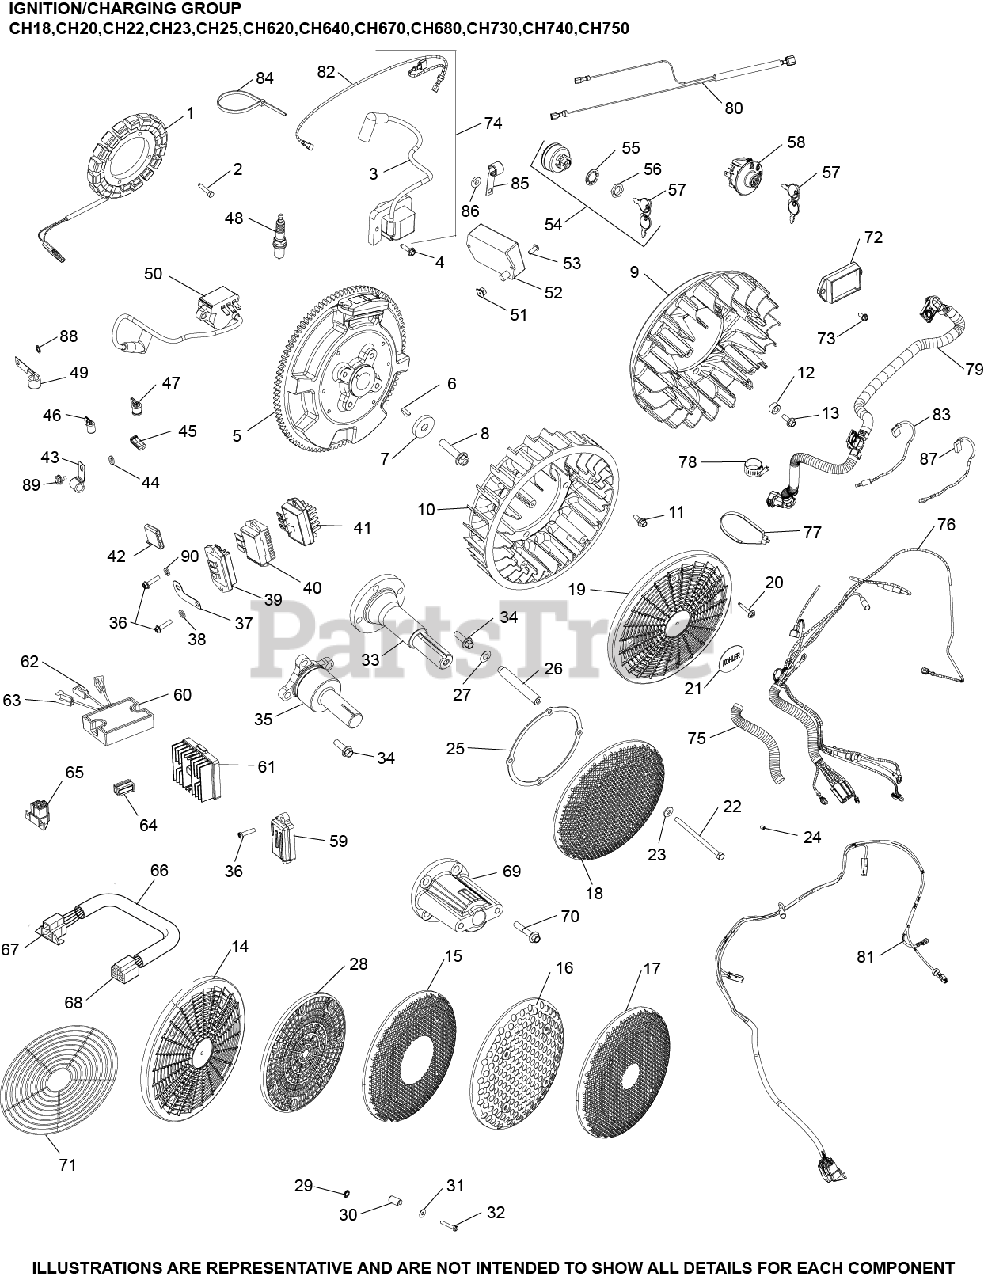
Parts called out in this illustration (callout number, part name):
1	KIT, 15 / 20 AMP STATOR
2	SCREW, M5X0.8X25 - (#25086402S)
3	KIT, MODULE IGNTN (CDI FIXED)
4	SCREW, FLG THD FRM M5X.8X20-(#25086399S)
6	KEY, 3/16" X 5/8"
7	WASHER, FLAT 13/32"
8	SCREW, FLG M10X1.5X45 - (#25086361S)
10	FAN USE 24 755 253-S
11	BOLT, SHOULDER
18	SCREEN, GRASS
19	KIT, GRASS SCREEN
20	SCREW, FLG SEMS M4X.7X25
36	SCREW, HEX FLANGE HI-LO
37	BRACKET, GROUND STRAP USE 24 518 12-S
40	REGULATOR, RECTIFIER USE 25 403 29-S
42	CONNECTOR, BODY (KM)-USE 25 155 41-S
43	CLIP, CABLE
44	WASHER, FLAT 1/4" (O.D. 1/2")
48	PLUG, SPARK (PRO SERIES)
82	LEAD, DUPLEX
83	LEAD, OIL SENTRY
87	LEAD, 20/25 AMP B+
